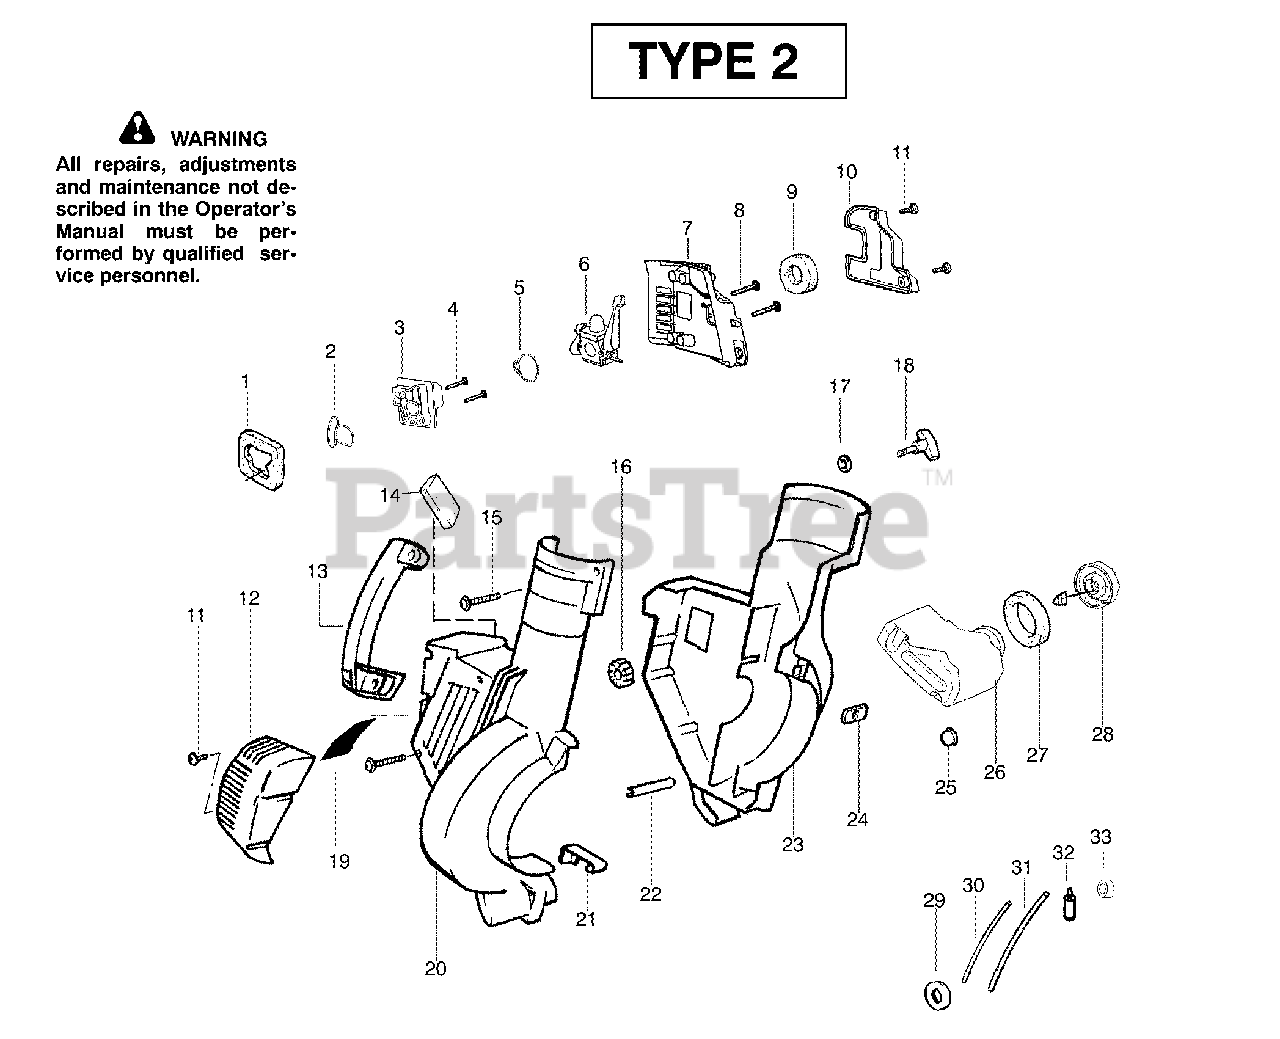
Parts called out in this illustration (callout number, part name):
1	Air Dam (Kit)
2	Gasket-Adapter (Kit)
3	Carburetor Adaptor
5	Gasket-Carburetor (Kit)
6	Kit-Carb Ass'y. (C1Q-W11)
6	Kit-Carb Ass'y. (C1Q-W11C)
8	Screw-Carb.
9	Filter-Air
10	Cover-Air Filter
12	Guard-Muffler
14	Foam - 71.12mm (Kit)
16	Isolator
18	Knob-Tube Clamp
19	Reflector-Heat (Kit)
20	Housing-Right
21	Spring-Cover Latch
22	Guide-Starter Rope
23	Housing-Left
25	Isolator-Crankcase
26	Assy-Fuel Tank
27	Gasket-Fuel Tank
28	Fuel Cap w/Retainer
29	Grommet-Shroud
30	Kit-Line Carb/Purge
31	Kit-Line Tank/Purge
32	Assy-Fuel Pick-up
33	Grommet-Fuel line (Kit)
